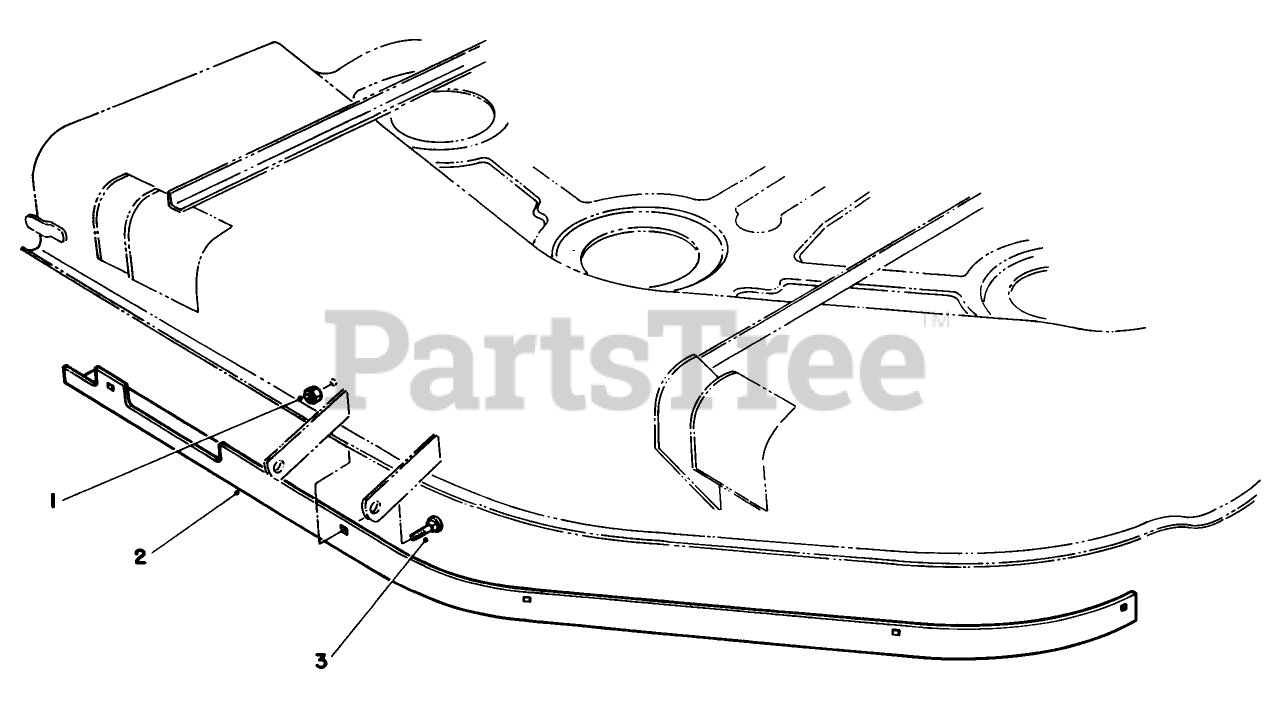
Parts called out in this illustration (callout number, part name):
1	NUT-LOCK, NI
2	Baffle
3	SCREW-CARR
